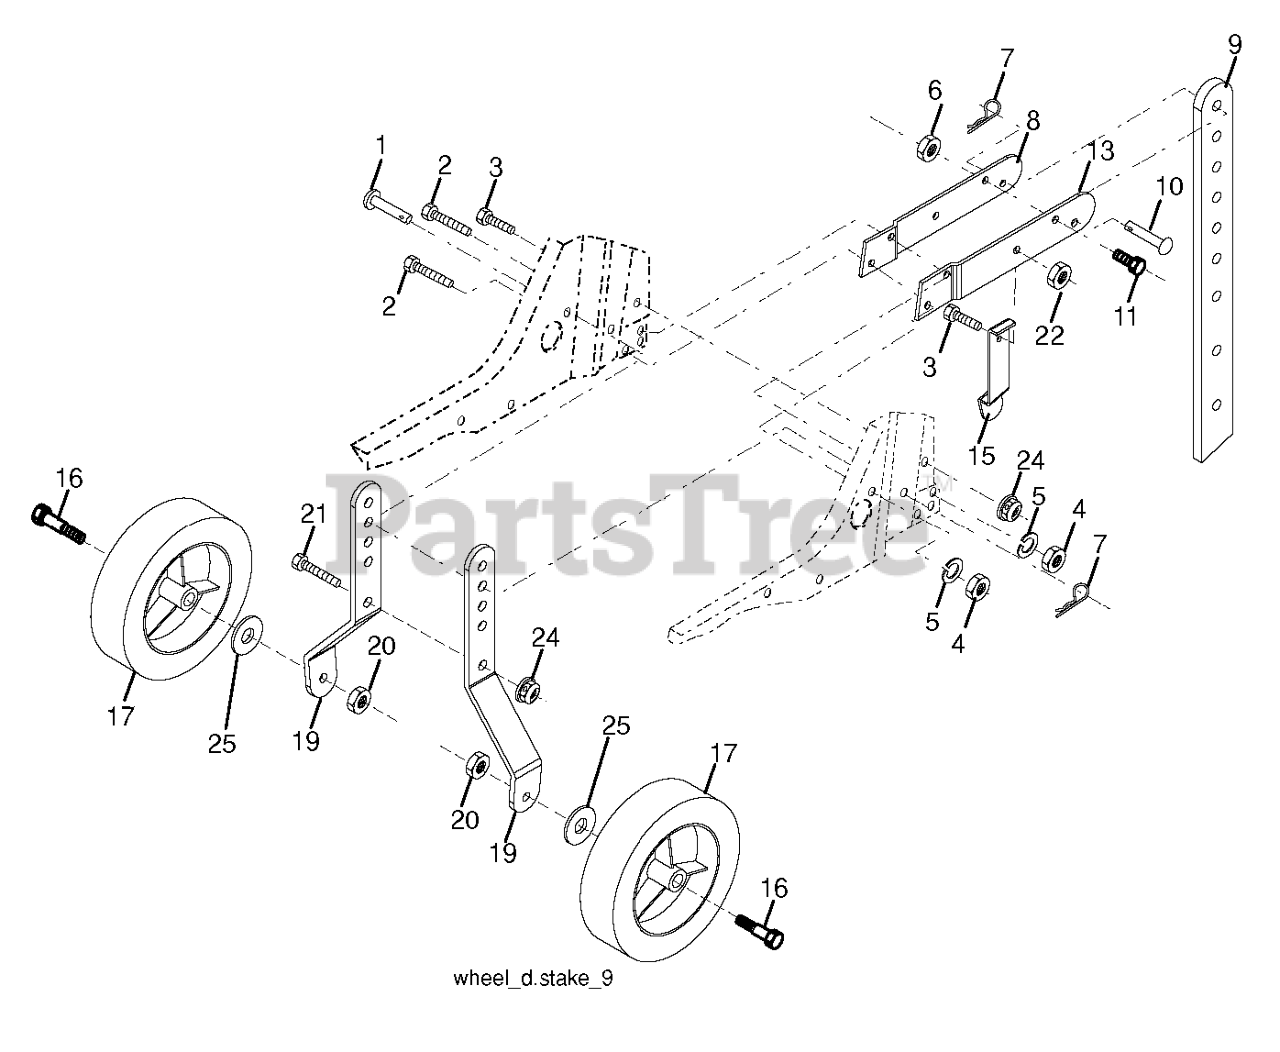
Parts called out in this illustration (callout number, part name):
1	PIN.CLEVIS.HD.25X1.75.TILLER
2	BOLT
3	BOLT.FIN.HEX.5/16-18X3/4
5	WASHER.LOCK.HVY.HLCL.SPR.5/16
6	NUT
7	SPRING TI
8	SUPPORT.STAKE.DEPTH.RH.BLACK
9	STAKE.DEPTH.13.25.W/9HOLES
10	RIVET.PAN.HD.DRILLED
11	BOLT
13	SUPPORT.STAKE.DEPTH.LH.BLACK
15	SPRING.STAKE
16	BOLT.SHOULDER
17	WHEEL.8X1.75.STORM.GREY
19	BRACKET.WHEEL.BLACK
21	BOLT RB
22	NUT.71038.31-18.HEX.NYLOCK
24	LOCKNUT-FLANGE 5/16-18
25	Washer 1 17/32 X 7/8 X 16 Ga
